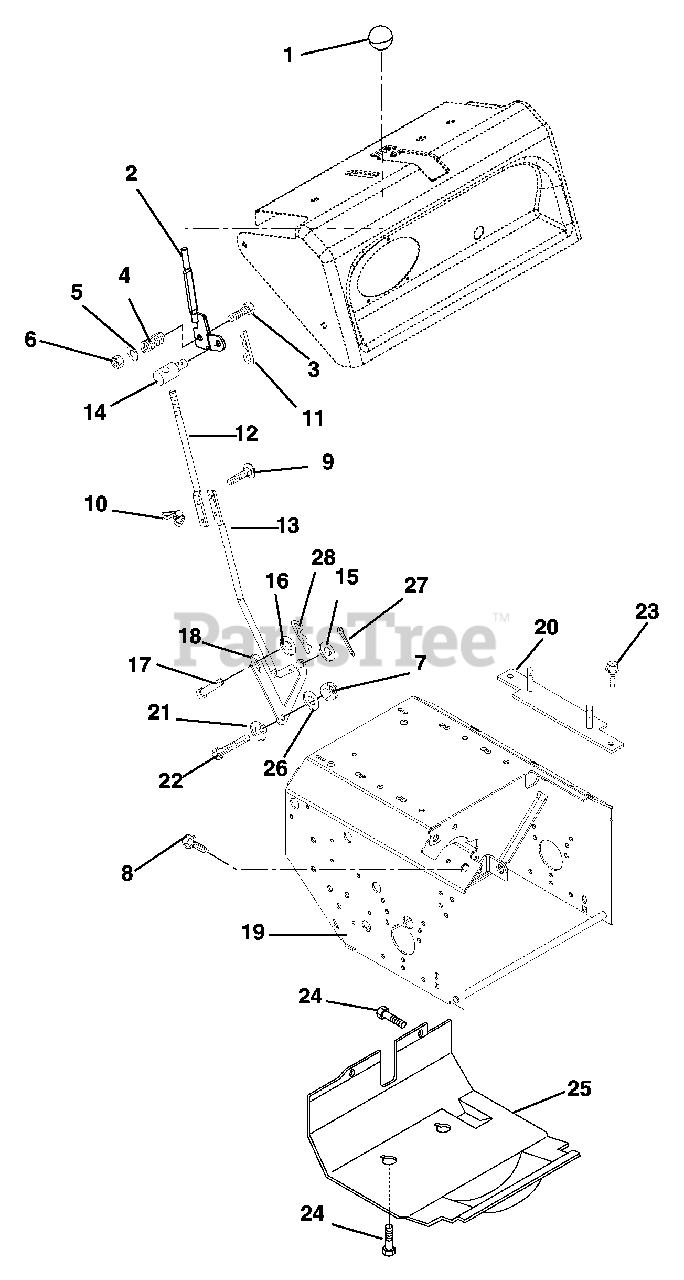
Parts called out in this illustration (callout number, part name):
1	Knob, Ball Black 1-.41, .38-16
2	Lever, Shift Weldment
3	Bolt, Hex .38-16 x 2.25 Grade 5
4	Spring, Compression .13 x .78 x 1.25
5	Washer, Flat Steel .44 x 1.00 x .083
6	Nut, Locking Center .38-16
7	Nut, Locking Center .31-18
8	Bolt, Hex Flanged Whiz Lock Head .38-16 x .75
9	Bolt, Round Head Square Neck .25-20 x 1.00 Grade 5
10	Nut, Locking Wing .25-20
11	Pin, Hair Internal .08 x .18 x 1.18
12	Rod, Shift-Upper
13	Rod, Shift-Lower
14	Pivot, Rod
15	Pin, Cotter .09 x .75
16	Washer, Flat Steel .38 x .81 x .023
17	Clevis Pin .37/.38 x .69
18	Arm, Shift
19	Main Frame
20	Bolt Strap
21	Bushing, Flange .325 x .500 x .327 x .875
22	Bolt, Hex .31-18 x 1.00 Grade 5
23	Screw, Tapping .25-20 x .37 Hex Washer Head
24	Screw, Tapping .312-12 x .375 Hex Washer
25	Cover, Bottom
26	Washer, Flat Steel .328 x .875 x .062
27	Washer, Flat-Steel .53 x 1.06 x .095
28	Pin, Hair
